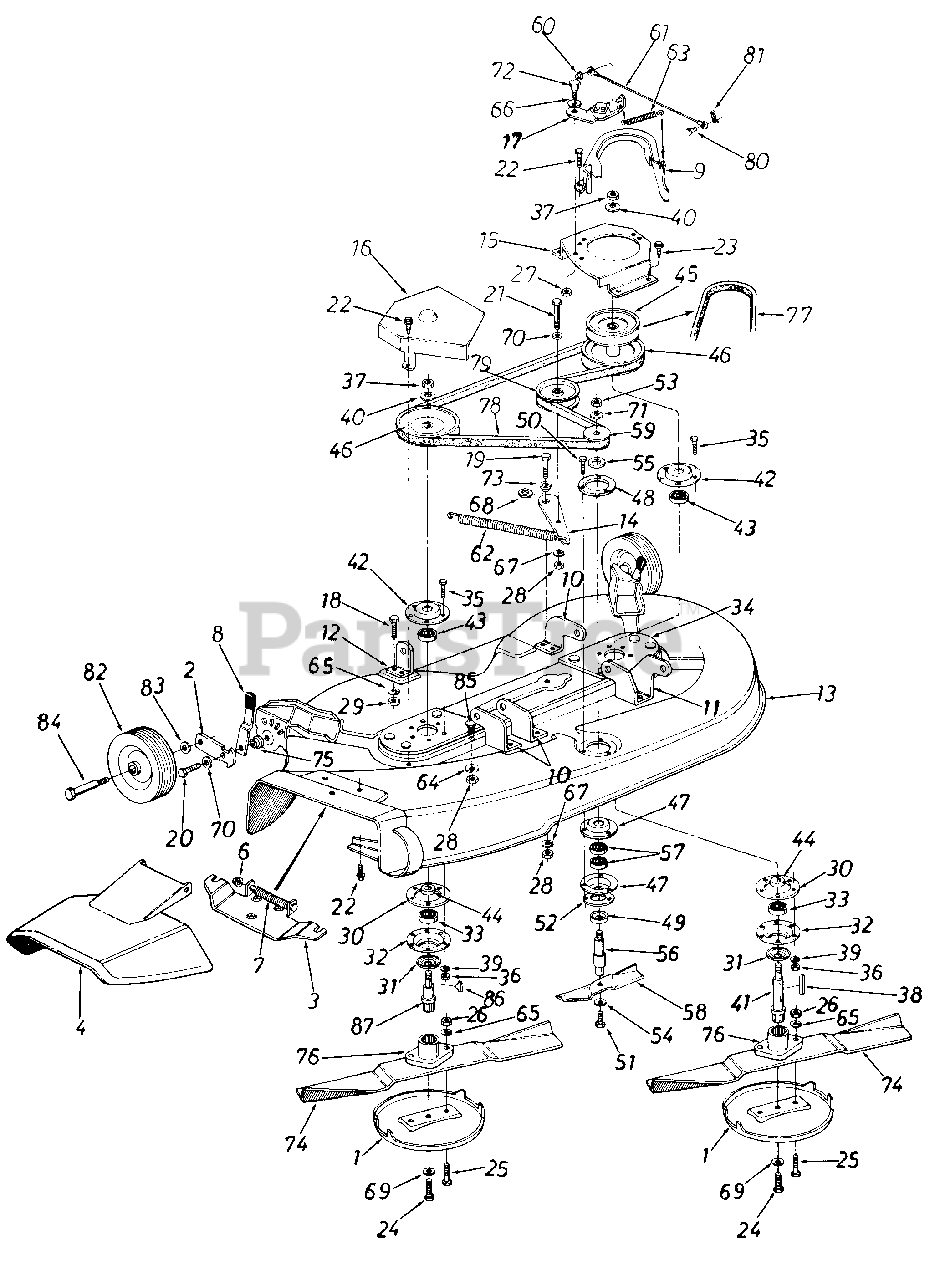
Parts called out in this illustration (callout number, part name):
1	Anti-Scalp Plate
2	Bar-Wheel Pivot
3	Adapter Plate
4	Chute Cover Ass'y.
6	Cap Speed Nut 1/4" Rod
7	Torsion Spring
8	Spring Lever Ass'y.
9	Belt Guard
12	Deck Hanger Bracket-1.91
13	44" Deck Ass'y.
14	Idler Bracket
15	Pulley Cover-L.H.
18	Hex Bolt 5/16-18 x .75" Lg.
19	Hex Bolt 3/8-24 x 1.00" Lg.*
20	Hex Bolt 3/8-24 x 1.25" Lg.
21	Hex Bolt 3/8-24 x 1.50" Lg.
22	Hex Wash. S-Tapp Scr. 1/4-20 x .50
23	Hex Wash. Hd. Tapp Scr. 5/16-18 x .75" Lg.
24	Hex Cent. L-Bolt 3/8-24 x .88" Lg.
25	Hex Bolt Special 5/16-24 x 1.0" Lg.
26	Hex Nut 5/16-24 Thd.
27	Hex Cent. L-Nut 5/16-18 Thd.
28	Hex Nut 3/8-24 Thd.*
29	Hex Nut 5/16-18 Thd.
30	Reinforcement Plate
31	Bearing Shield
32	Open Brg. Housing 1.85 I.D.
33	Ball Brg. .787" I.D. x 1.85" O.D. x .551
34	Spindle Mounting Plate Ass'y.
35	Hex Bolt Special 5/16-24 x 1.0" Lg.
36	Hex Nut 5/16-24 Thd.
37	Hex Jam Nut 5/8-18 Thd.
38	Sq. Key 3/16" x 3/16 x 2.25" Lg.
39	L-Wash. 5/16" I.D.
40	Bell-Wash. .630" I.D. x 1.25" O.D.
41	44" Deck Blade Spindle
42	Bearing Housing 1.85" I.D.
43	Ball Brg. .787" I.D. x 1.85" O.D. x .551
44	Spacer 1.0" O.D. x .790" I.D.
45	5/8 "V"-Pulley .79" I.D. x 5.75" O.D.
46	"V"-Pulley .79" I.D. x 6.50" O.D.
47	1-3/8" I.D.-Bearing Housing
48	Reinforcement Plate
49	Bearing Shield
50	Hex Sems Scr. 1/4-28 x .625" Lg.
51	Hex Cent. L-Bolt 3/8-24 x .88" Lg.
52	Ring Nut 1/4-28 Thd.
53	Hex Jam Nut 1/2-20 Thd.
54	Bell-Wash. .400" I.D. x .88" O.D.
55	Fl-Wash. .635" I.D. x 1.04" O.D.
56	6.5" Blade Spindle
57	Ball Brg. .62" I.D. x 1.38" O.D. x .44
58	6.50" Blade
59	1/2" "V"-Pulley Half .625" I.D. x 2.25" O.D.
60	Cap Speed Nut 1/4" Rod
61	Brake Cable 11.75" Lg.
62	Extension Spring .73" O.D. x 4.31" Lg.
63	Ext. Spr. .50" x 2.5" Lg.
64	Bell-Wash. .400" I.D. x .88"O.D.
65	L-Wash. 5/16" I.D.
66	Spring Wash. .445" I.D. x .75" O.D.
67	L-Wash. 3/8" I.D.
68	Spring Wash. .625" I.D. x .885" O.D.
69	L-Wash. 3/8" I.D.
70	Bell-Wash. .400" I.D. x 1.13" O.D.
71	Bell-Wash. .505" I.D. x 1.00" O.D.
72	Shld. Bolt .437" Dia. x .180
73	Shld. Spacer.625" I.D.
74	21" Blade
75	Shld. Spacer
76	Blade Adapter
77	"V"-Belt 1/2" x 52.0" Lg.
78	"V"-Belt 1/2" x 74.0" Lg.
79	Fl-Idler w/Flanges 3.50" O.D.
80	Clevis Pin 1/4" Dia. x .53" Lg.
81	Intern. Cotter Pin 5/16" Dia.
82	Deck Wheel 6.0" x 1.38
83	Bell-Wash. .400" I.D. x .88" O.D.
84	Shld. Bolt 3/8-16 x 1.41
85	Rib Neck Bolt
86	Sq. Key 3/16" x 3/16" x .75"
87	44" Deck Blade Spindle
